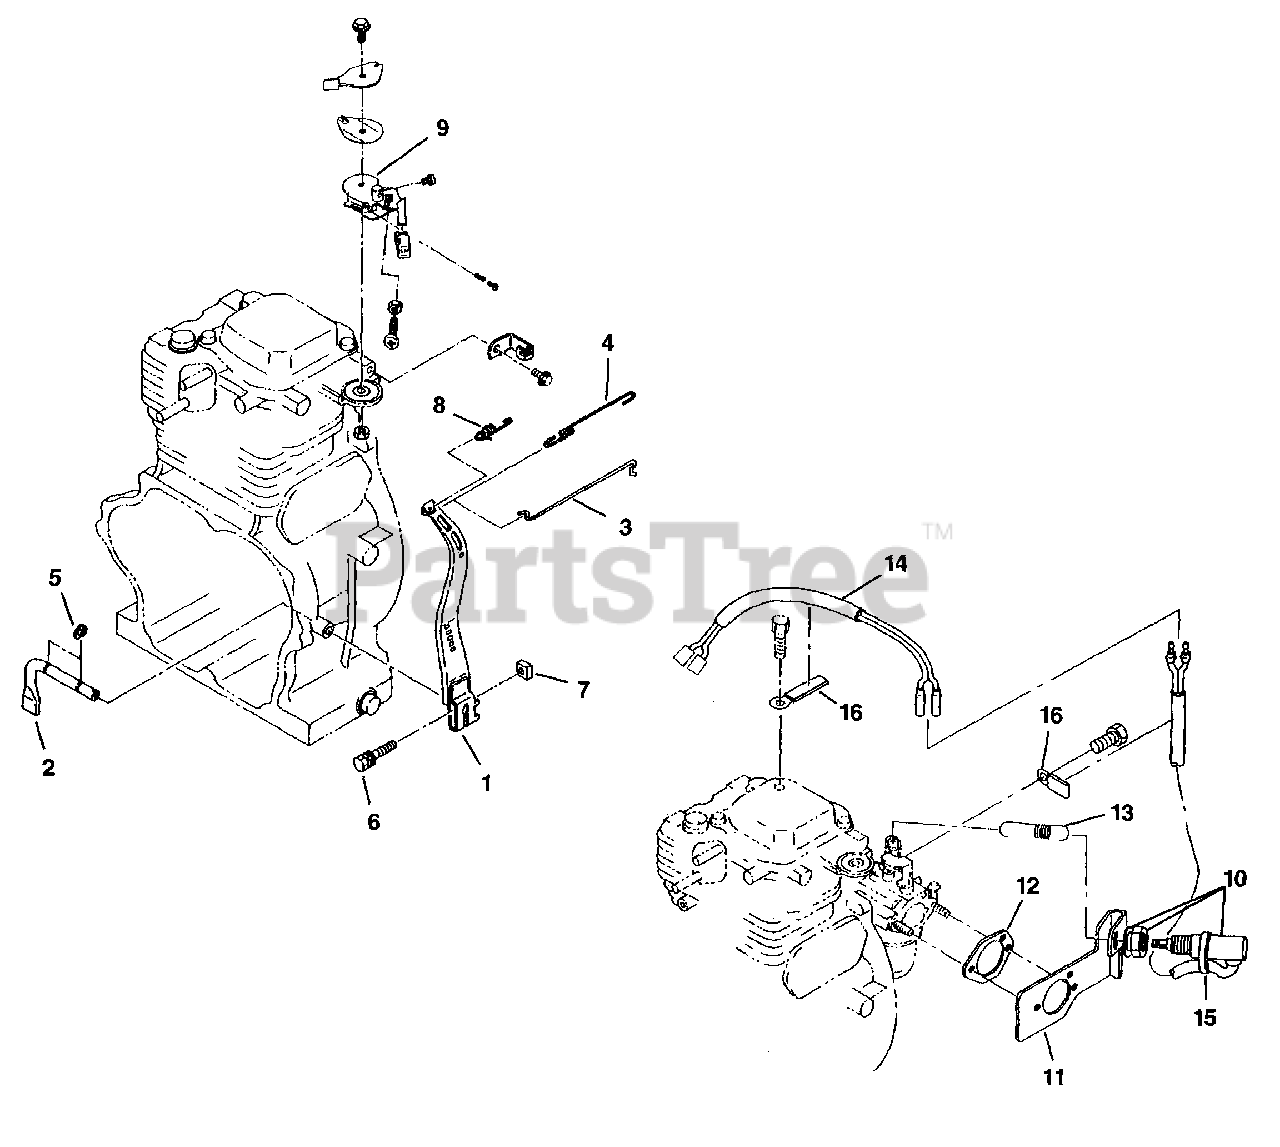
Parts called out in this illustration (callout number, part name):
1	Governor lever
2	Governor shaft
3	Governor rod
4	Rod spring
6	Bolt & washer M6 x 12
8	Governor spring
9	Speed control ay
10	Solenoid cp
11	Bracket 2
12	Gasket, air cleaner
15	Wire band
